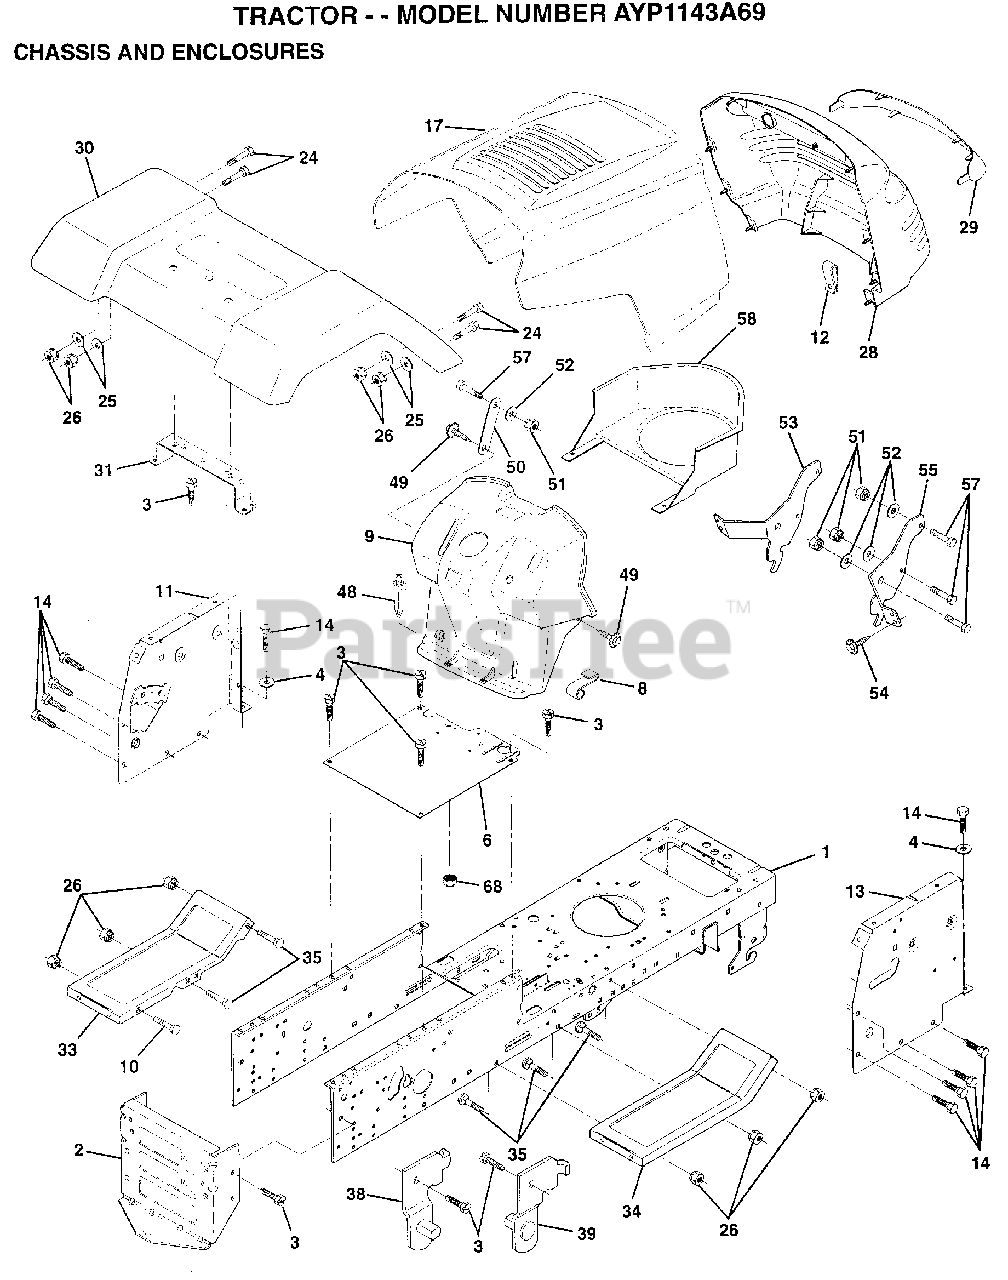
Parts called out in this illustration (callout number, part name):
1	CHASSIS.WLD.11GA
3	SCREW
4	WASHER
8	"CLIP,INSULATOR"
11	PANEL.DASH.LH.
12	CLIP.TINNERMAN
13	PANEL.DASH.RH
14	SCREW LT
24	BOLT
25	WASHER
26	NUT
29	LENS GRILLE
30	FENDER
31	BRKT FENDER
33	FOOTREST LH
35	BOLT
38	BRACKET ASM LH
39	BRACKET ASM RH
48	RIVET.PUSH.PLATE
49	SCREW HEX CRT
50	BRACE SUPT DASH
51	NUT
52	WASHER
53	BRACKET.GRILLE.LH
55	BRACKET.GRILLE.RH
58	AIR DUCT
68	NUT
